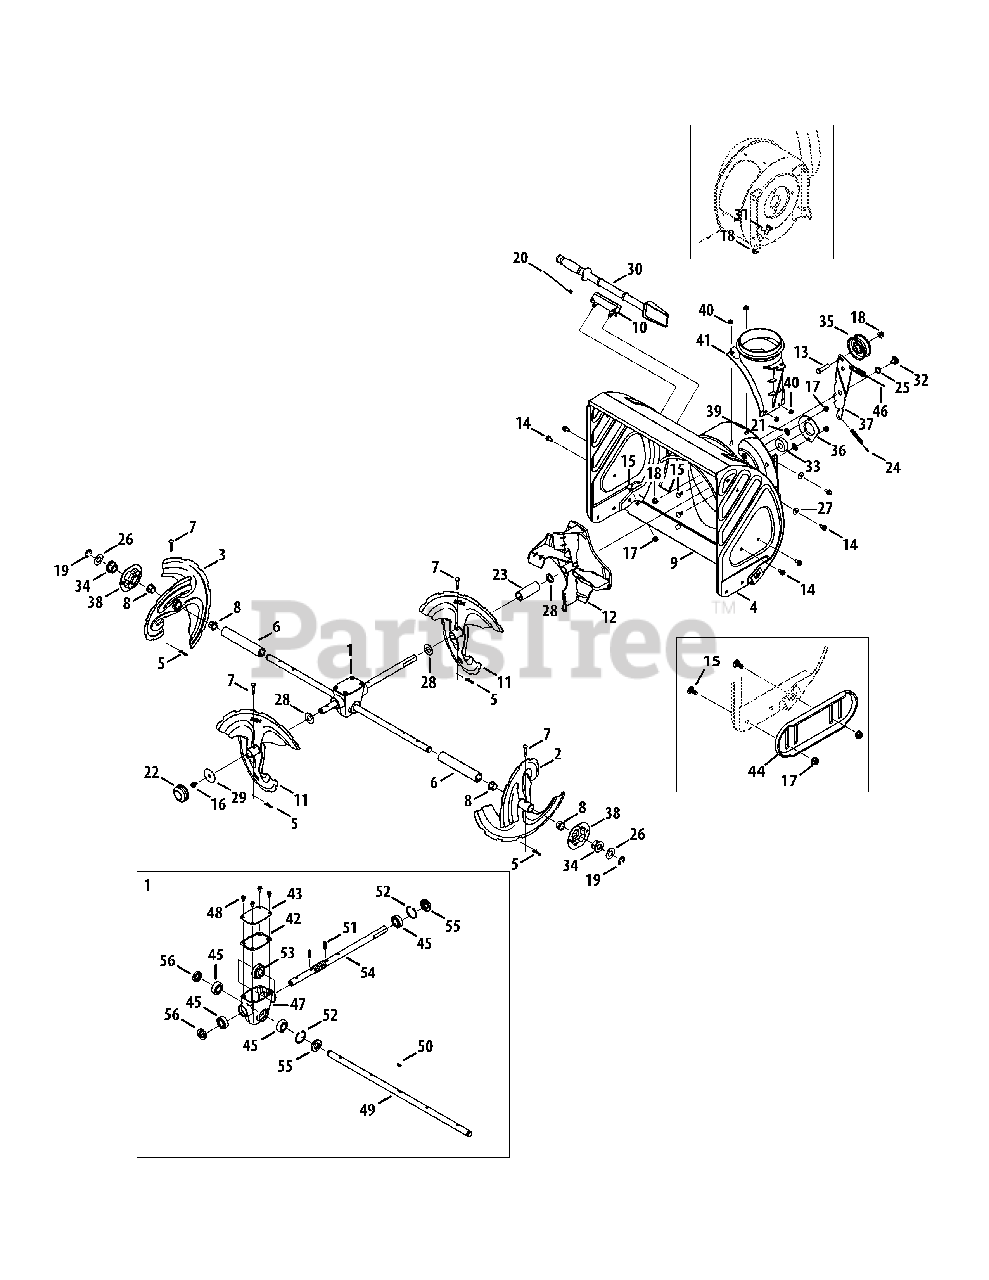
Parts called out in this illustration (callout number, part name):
1	Gearbox Assembly, Auger, 24"
2	Spiral Assembly - LH, 24"
3	Spiral Assembly - RH, 24"
4	Auger Housing, 24"
5	Bow Tie Cotter Pin
6	Spacer, 1.25 OD x .75 ID x 5.8 (24")
8	Flange Bushing, .800 x .910
9	Shave Plate, 24"
10	Clean-out Tool Mtg. Bracket
11	Accelerator Assembly
12	Impeller Assembly
13	Hex Bolt, 3/8-16 x 1.75
14	Screw, 5/16-18 x .750
15	Carriage Bolt, 5/16-18 x .750
16	Hex Washer Screw, 5/16-18 x .500
17	Flange Lock Nut, 5/16-18
18	Flange Lock Nut, 3/8-16
19	E-ring, .75
20	Cable Tie
21	Push-On Nut, .25 Dia.
23	Spacer, 1.35 OD x .76 ID x 2.755
24	Extension Spring, .38 OD x 4.59
25	Wave Washer, .625 x .885 x .0175
26	Flat Washer, .76 x 1.49 x .06
27	Bell Washer, .340 x .872 x .060
28	Flat Washer, .793 x 1.24 x .06
29	Flat Washer, .406 x 1.92 x .060
30	Clean-Out Tool
31	Shoulder Screw, 3/8-16 x .496 x .336
32	Shoulder Screw, 3/8-16 x .625 x .17
33	Flange Ball Bearing, .75 x 1.85
34	Hex Flange Bearing, .75 ID
35	Flat Idler Pulley
36	Bearing Housing
39	Carriage Screw, 1/4-20 x 0.75
40	Flange Lock Nut, 1/4-20
41	Chute Adapter
42	Gearbox Gasket
43	Gearbox Cover
44	Deluxe Slide Shoe
45	Ball Bearing, .75 x 40 x 12
46	Auger Clutch Cable
47	Auger Housing
48	Screw, 1/4-20 x 0.75
49	Axle, Auger, 24"
50	Hi-Pro Key
51	Pin, Roll, .25 x 1.0
52	Retainer Ring
53	Worm Gear, 20T
54	Worm Shaft
55	Seal, .75 x 40mm x .25
56	Seal, .75 x 1.375 x .25
